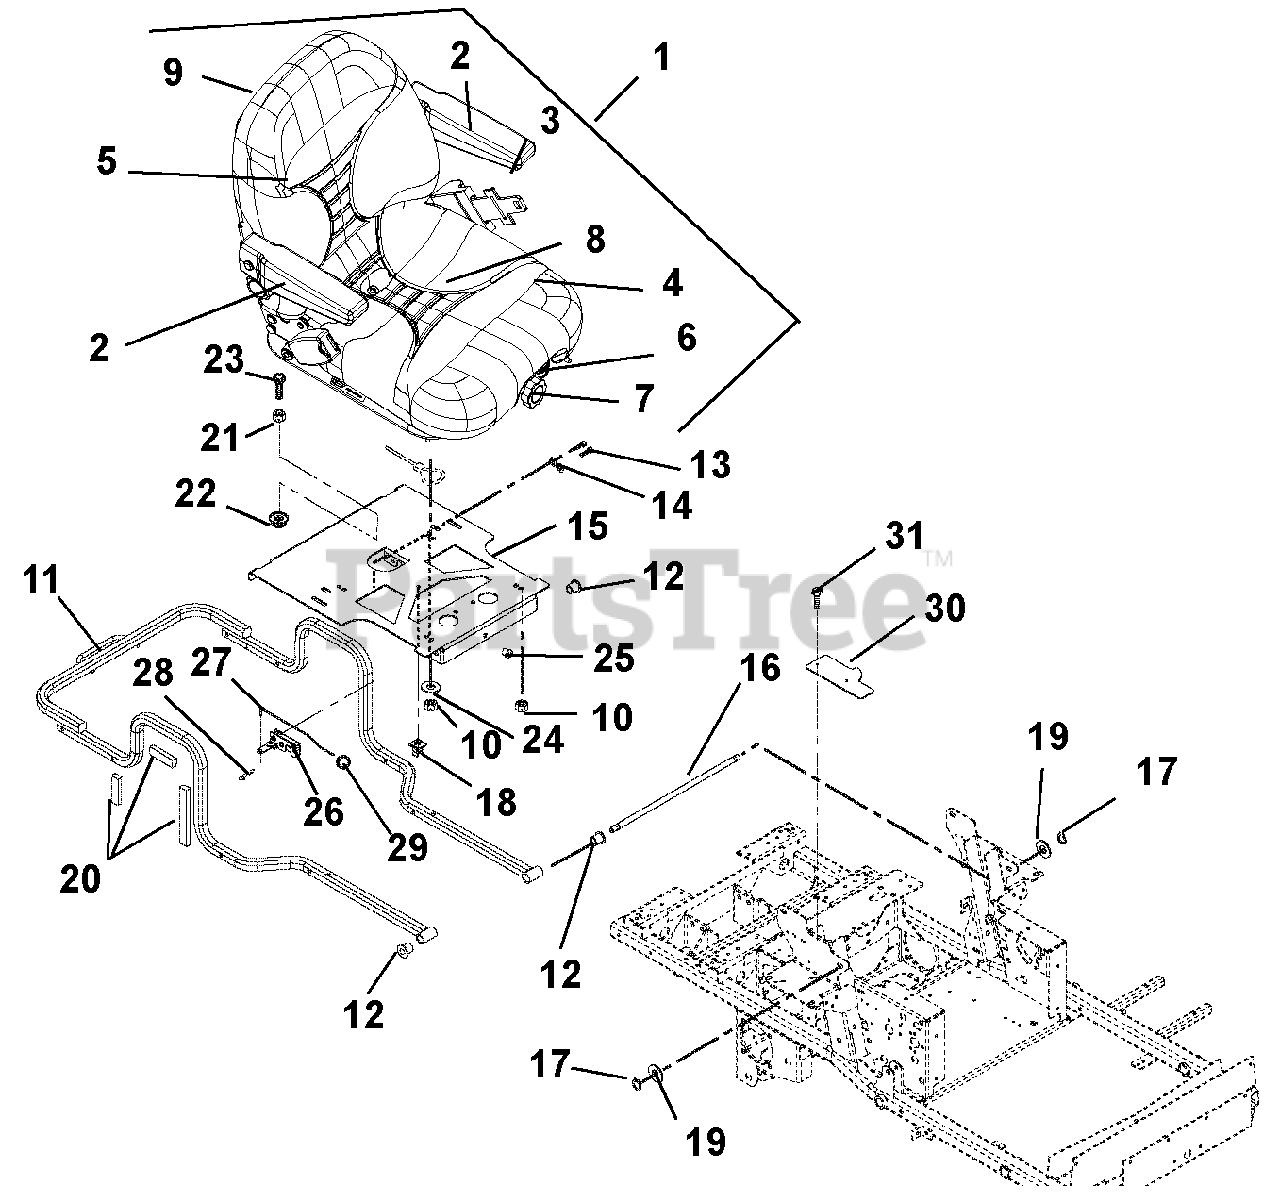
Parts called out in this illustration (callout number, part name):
1	Seat, Gray, with Seat Belt
2	Kit, Arm Rest, Plush, Pair
3	Kit, Retractable Safety Belt
4	Kit, Seat Cushion, Light Gray
5	Kit, Back Cushion, Light Gray
6	Kit, Seat Slide
7	Kit, Seat Knob
8	Kit, Spring and Saddle
9	Kit, Seat Back Panel
10	Nut, Locking Top Flange .31-18
11	Weldment, Hood Frame
12	Bushing, Flange .515 x .750 x .745 x 1.00
13	Bolt, Hex .25-20 x 1.00 Grade 5
14	Washer, Locking .25 x .062 Regular
15	Plate, Seat 200 XDZ with Latch
16	Rod, Seat Frame Pivot
17	Ring, Retaining External .500 x .050
18	Clip, Routing
19	Washer, Flat Steel .531 x 1.06 x .095
20	Tape, VHB
21	Nut, Hex .50-13
22	Nut, Locking Top Flange .50-13
23	Bolt, Hex .50-13 x 1.50
24	Washer, Flat Steel .344 x 1.125 x .135
25	Bushing, Polyliner .38 Snapin
26	Latch, Rotary-Push To Close
27	Rod, Seat Latch Release
28	Pin, Cotter .09 x .75 Extended Prong Square Cut
30	Plate, Block Off
31	Screw, Tapping .25-20 x .75 Hex Washer Head
